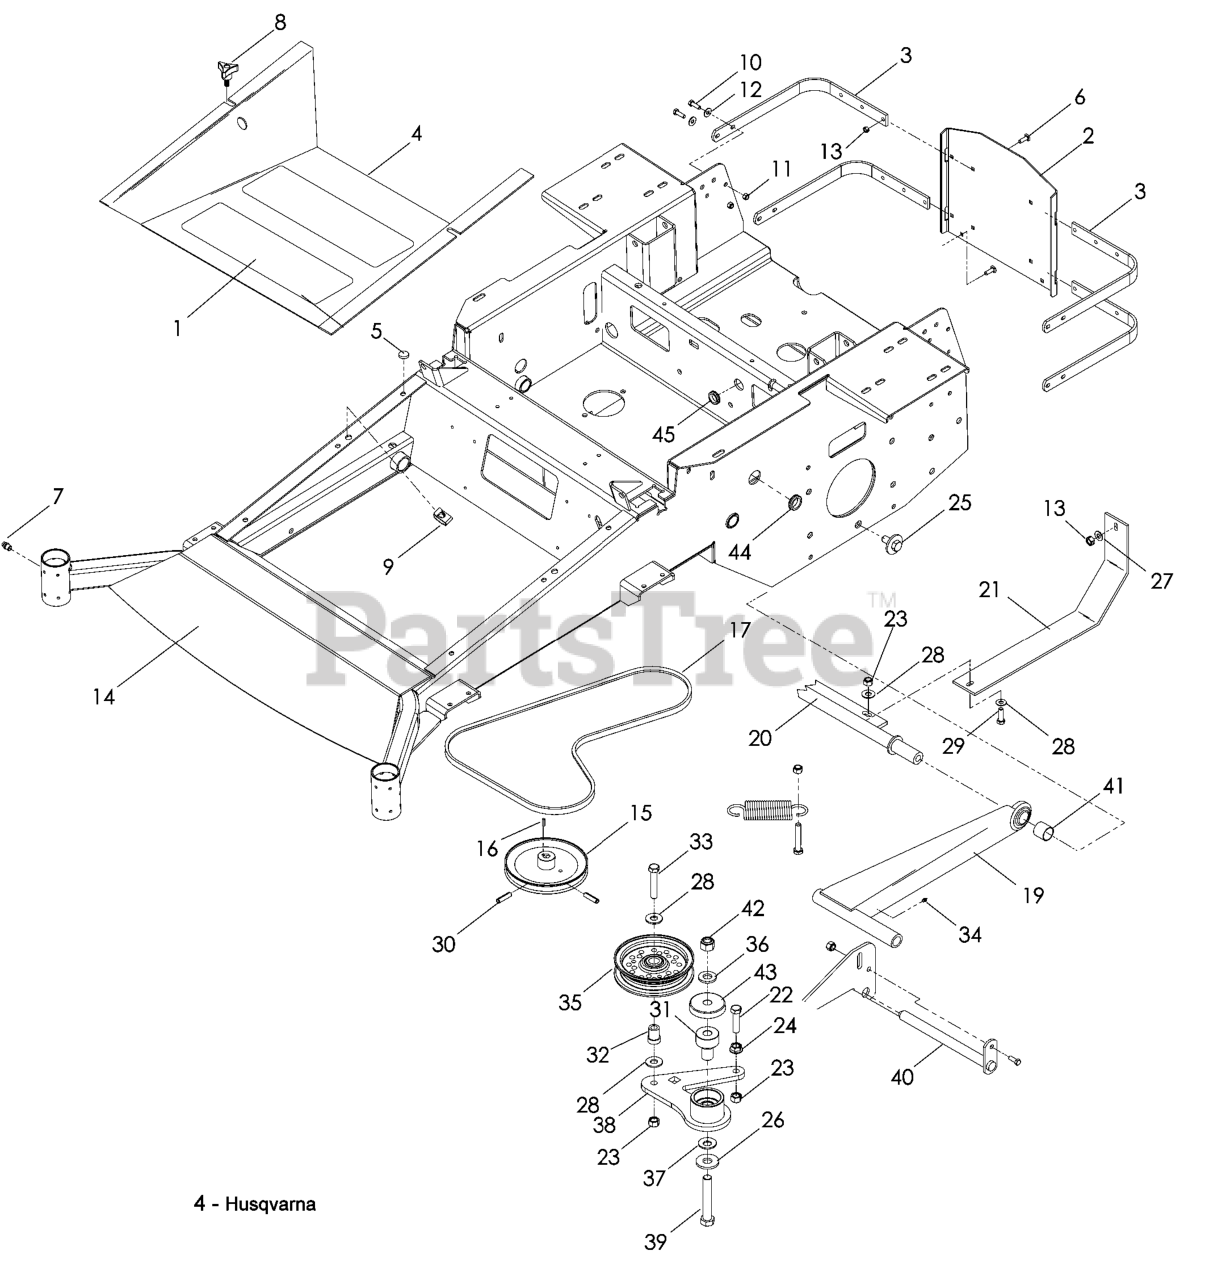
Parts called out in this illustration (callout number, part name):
1	ANTI-SKID PAD
2	XP GUARD, BLACK
3	ENGINE SHROUD BRKT
4	FOOT PLATE WIDMT
5	GROMMET, BUMPER
6	BOLT 5/16C X 3/4" CARRIAGE
7	ZERK
8	KNOB W/STUD
9	U-CLIP 5/16-18 NUT RETAINER
10	HCS 5/16C X 1
11	NUT 5/16 NYLOC
12	WASHER 5/16 FLAT
13	NUT 5/16C CENTERLOCK
14	FRAME W/DECALS 52/61
16	KEY 5 MM SQ X 25 MM
17	BELT, PUMP
20	CROSS SHAFT, STRUT - BLK
21	SKID PLATE
22	HCS 3/8C X 1 1/2
23	NUT 3/8-16 NYLOC
24	NUT 3/8C WHIZ
25	BLADE BOLT/WASHER
26	WASH USS FLAT 1/2
27	WASHER 5/16 FLAT
28	WASHER 3/8 FLAT
29	HCS 3/8-16X1.GRD.5.ZD
30	5/16 DIA ROLL PIN
31	PIVOT, BEARING
32	BUSHING, IDLER FLANGE
33	HCS 3/8C X 2
34	ZERK
35	IDLER PULLEY
36	WASHER 1/2" FLAT
37	CONTACT BELLSPR 1/2
38	ARM, IDLER - W/BEARINGS
39	SCREW, 1/2C X 3 HEX CAP
41	SPACER, STRUT
42	NUT 1/2-13 HEX NYLOC ZD
43	SHIELD, DUST
44	RUBBER GROMMET
45	GROMMET, FUEL LINE
